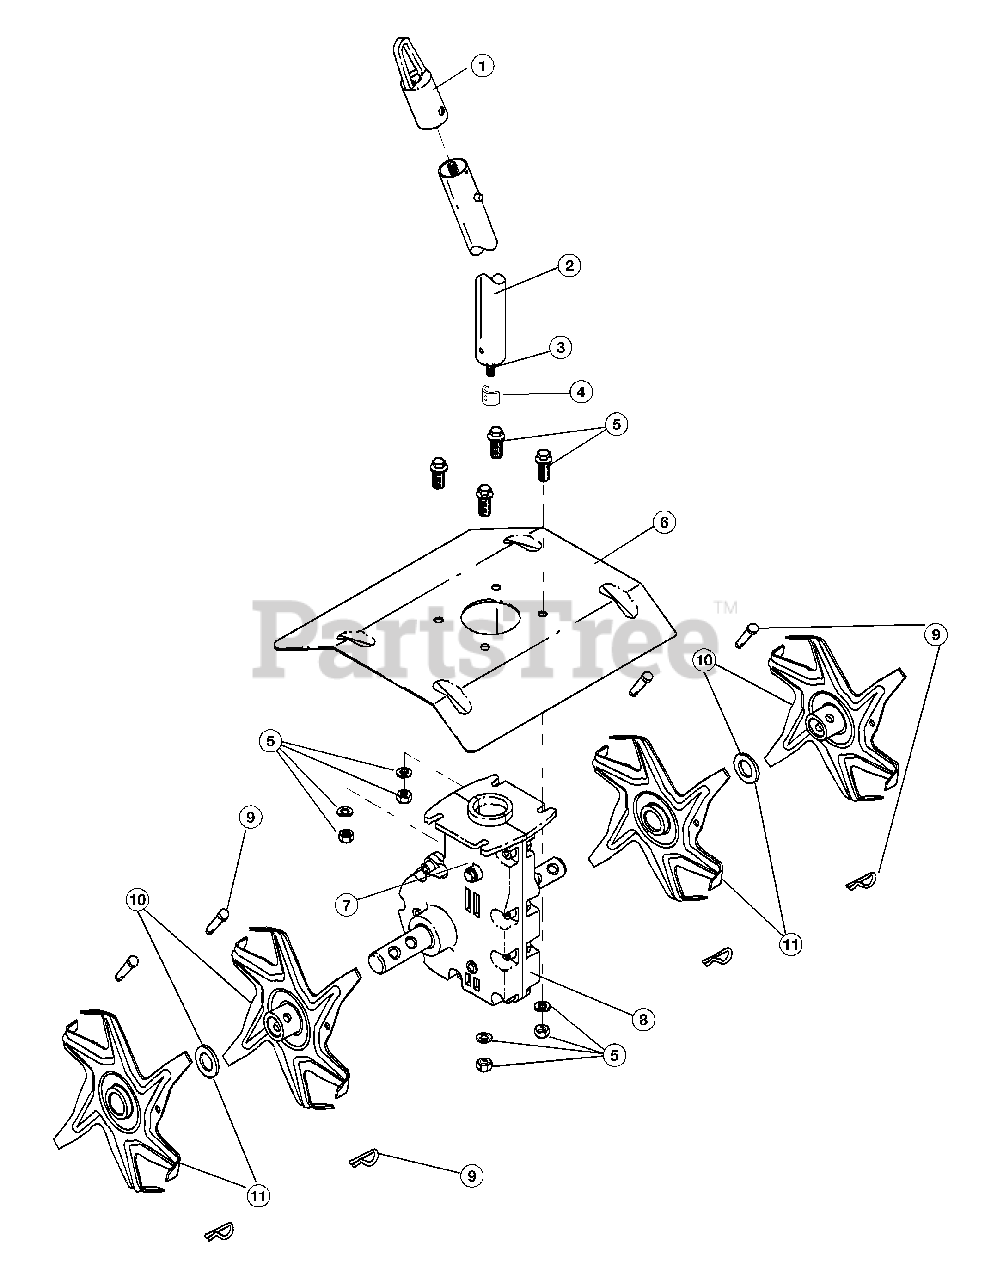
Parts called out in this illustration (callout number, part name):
1	Accessory Hanger
2	Drive Shaft Housing Assembly
3	Flexible Drive Shaft
4	Retainer Sleeve
5	Guard Mounting Hardware Set
7	Bolt
8	Gear Box Assembly
9	Tine Fastener Assembly
10	Tine Assembly
11	Tine Assembly
